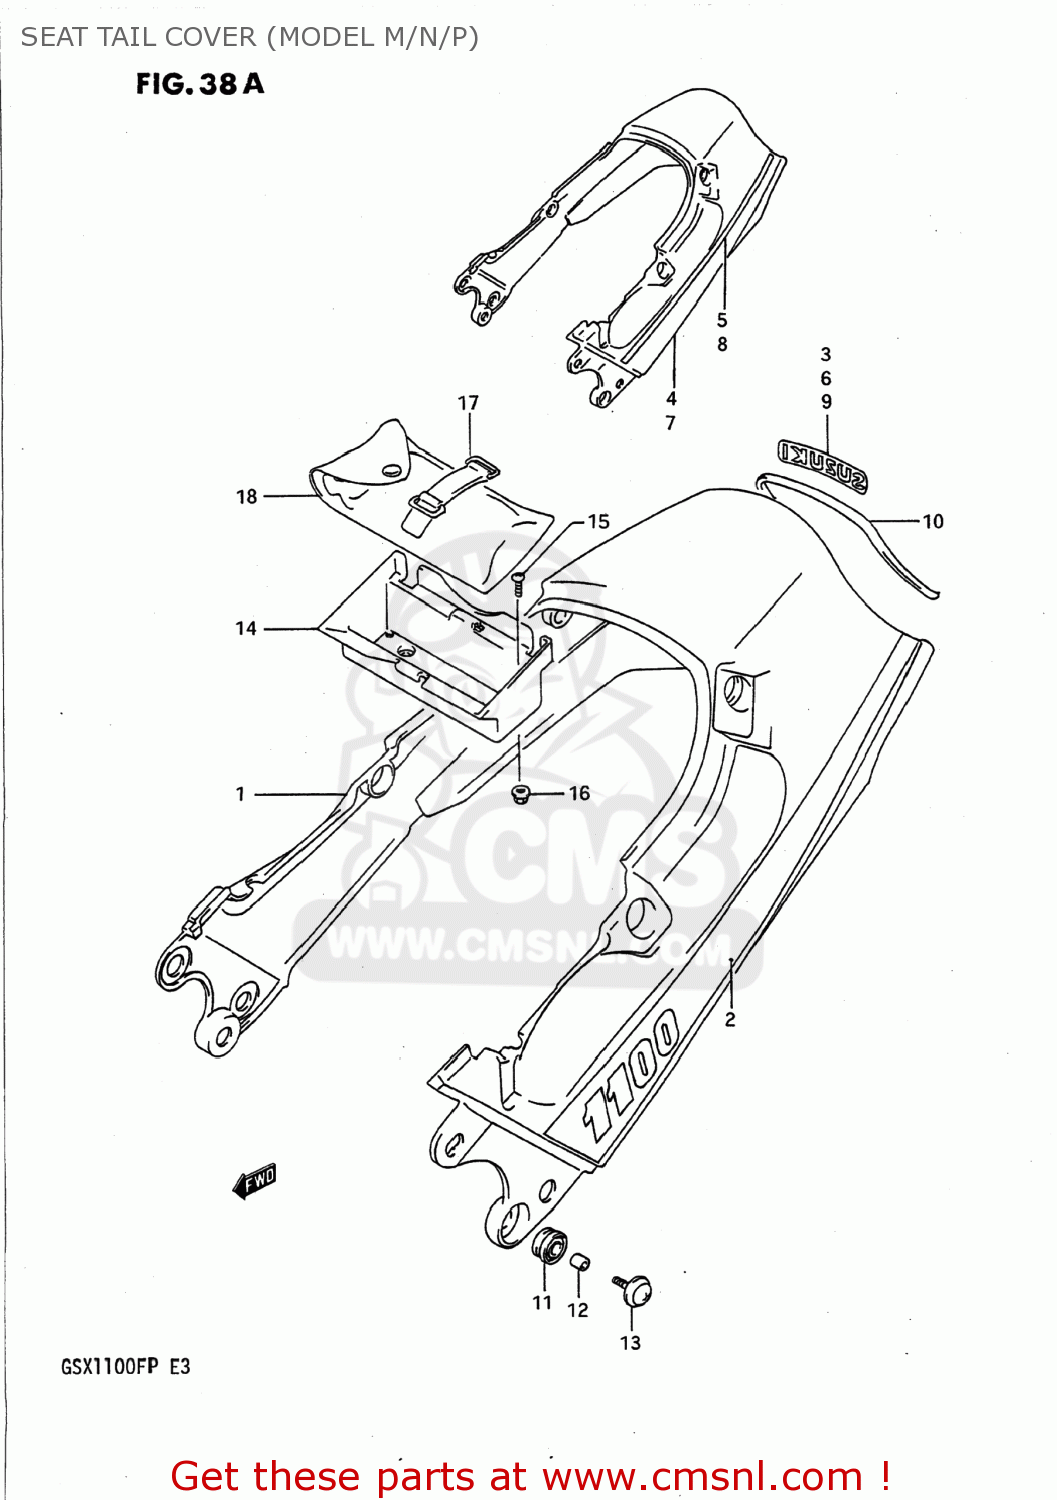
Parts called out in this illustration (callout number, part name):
1	COVER SET,SEAT TAIL
2	TAPE SET,SEAT TAIL COVER
3	EMBLEM,SUZUKI
4	COVER SET,SEAT TAIL
5	TAPE SET,SEAT TAIL COVER
6	EMBLEM (SUZUKI)
7	COVER SET,SEAT TAIL
8	TAPE SET,SEAT TAIL COVER
9	EMBLEM (SUZUKI)
10	MOLDING,SEAT TAIL COVER
11	CUSHION,SEAT TAIL COVER SIDE
12	SPACER (6.1X8X8)
13	SCREW(6X20)
14	HOLDER,TOOL
15	SCREW
16	NUT
17	BAND
18	TOOL ASSY
